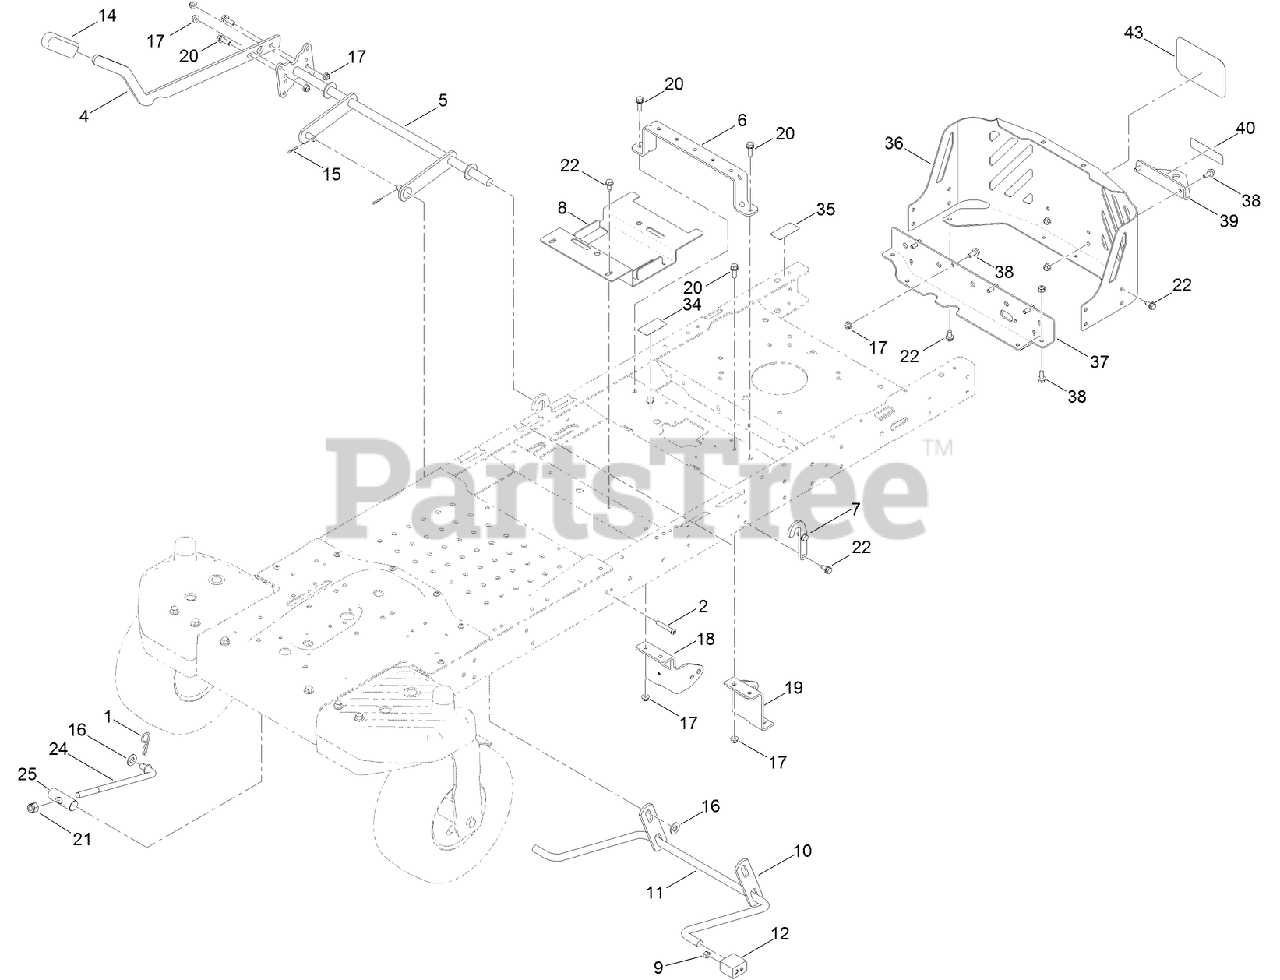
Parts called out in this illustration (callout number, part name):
1	PIN-COTTER
2	SCREW-HSBH
4	LEVER-LIFT
5	LIFT-DECK, NARROW
6	BRACE-SEAT, REAR (NARROW)
7	BRACKET-LIFT
8	BRACKET-BATTERY
9	NUT-LOCK, NI
10	LINK-LIFT
11	ARM-LIFT, REAR
12	BLOCK-PIVOT
14	GRIP-LEVER
15	PIN-COTTER
16	WASHER-FLAT
17	NUT-HF, NI
18	MOUNT-HYDRO, FRONT (RH)
19	MOUNT-HYDRO, FRONT (LH)
20	SCREW-HHF
21	NUT-HEX
22	SCREW-HWHTF
24	ROD-MOUNT, DECK
25	PIN-PIVOT
34	DECAL-LOCATION, SERVICE DEALER
35	DECAL-BYPASS
36	GUARD-ENGINE, NARROW
37	CROSSMEMBER-REAR, NARROW
38	SCREW-HHF
39	BRACKET-HITCH
43	DECAL
